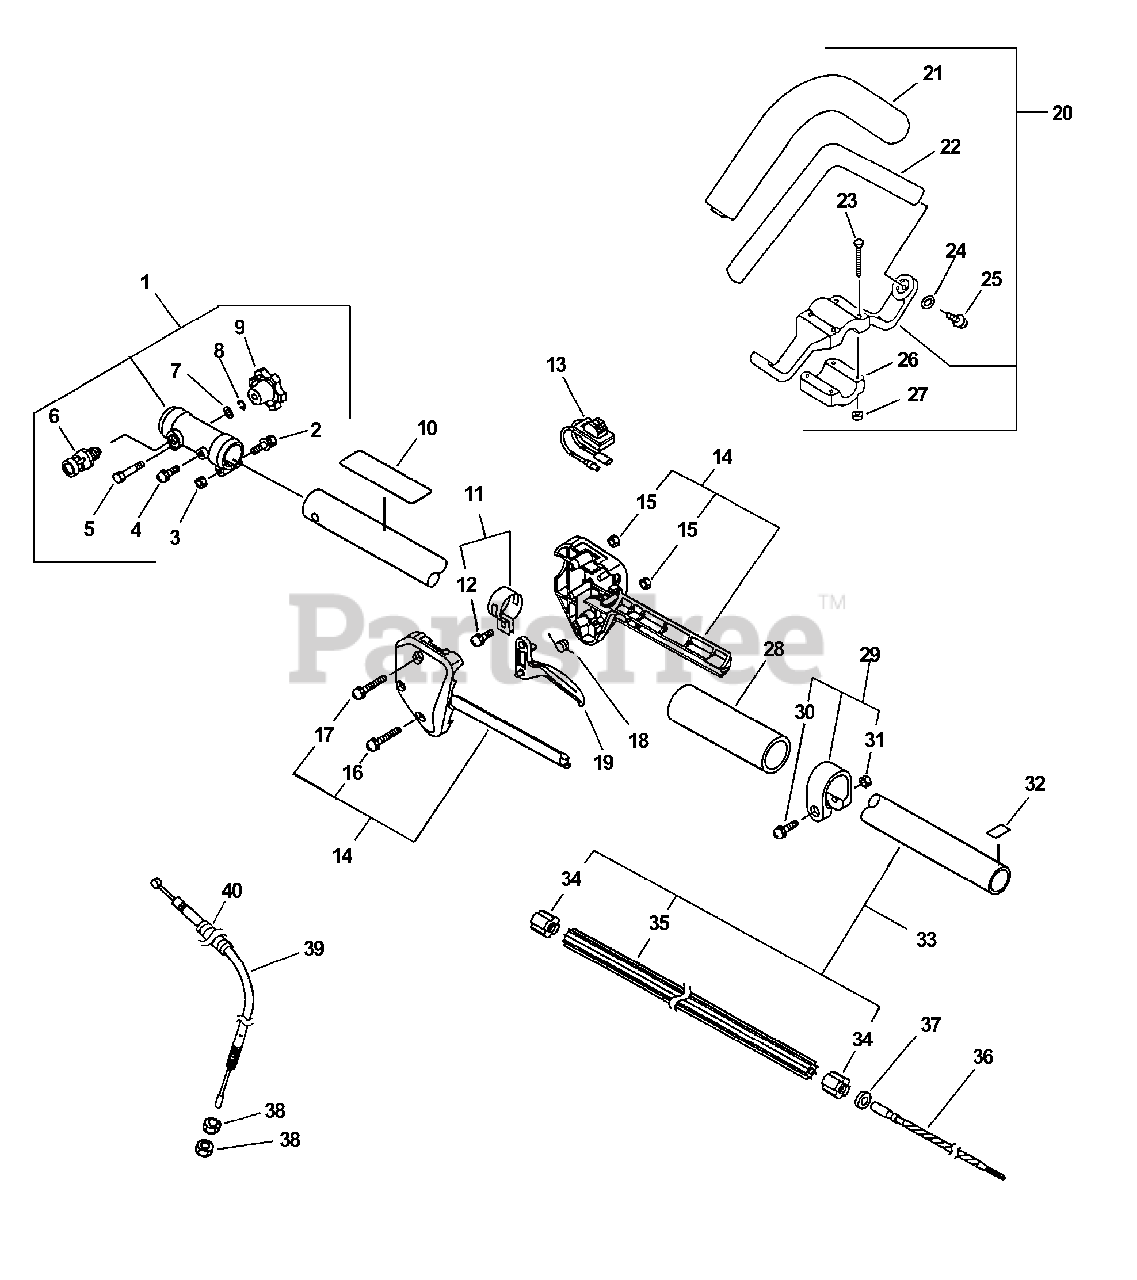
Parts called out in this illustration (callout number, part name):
1	COUPLER ASSY
2	SCREW - 5X30
4	SCREW - 5X12
5	BOLT - 5X35
6	LATCH ASSY
7	WASHER - 5
8	LOCKWASHER - 5
9	KNOB, FASTENER
10	LABEL - CAUTION -- SPANISH
11	CLAMP KIT
12	SCREW - 5X14
13	IGNITION SWITCH ASSY
14	CONTROL HANDLE KIT
16	SCREW - 5X25
17	SCREW - 5X35
18	SPRING, TRIGGER
19	TRIGGER, THROTTLE
20	HANDLE ASSY - FRONT
21	GRIP, HANDLE
22	HANDLE - FRONT
23	SCREW - 5X35
24	WASHER - 5
25	SCREW - 5X20
26	BRACKET, HANDLE - LOWER
28	GRIP, HANDLE
29	CLAMP KIT
30	SCREW - 5X28
32	LABEL - ALIGNMENT
33	MAIN PIPE ASSY
35	LINER - FLEXIBLE
36	DRIVESHAFT - FLEXIBLE -- UPPER
39	CABLE, THROTTLE
40	TUBE
